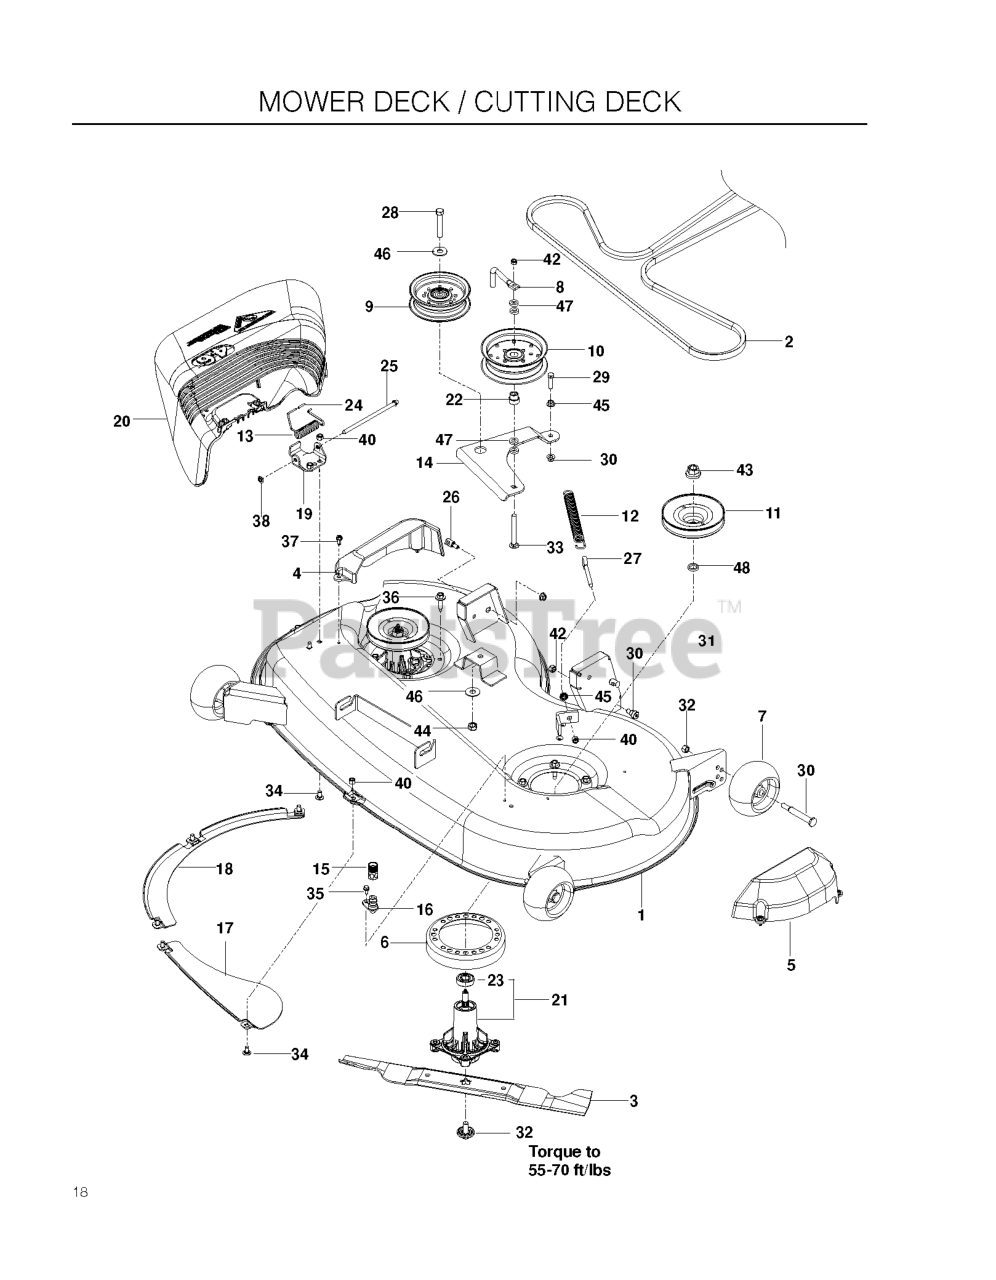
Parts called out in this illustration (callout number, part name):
1	DECK W/DECALS 46" ORANGE
3	BLADE.MOWER.46".HI.LIFT
4	COVER.MANDREL.RH.46"
5	COVER.MANDREL.LH.46"
6	STRIPPER-ROUND-UNIVERSAL
7	GAUGE WHEEL
8	BELT KEEPER 5"
9	PULLEY.IDLER.MWR.STATI.LH
10	PULLEY, IDLER
11	RP.PULLEY, DECK
12	SPRING, DECK BELT
13	TORSION SPRING
14	ARM, IDLER BLK
15	COUPLING.QUICK CONNECT
16	PORT.WASHOUT
17	BAFFLE CENTER FRONT
18	BAFFLE FRONT RH
19	BRKT.DEFLECTOR.38"2005+
20	SHIELD.DEFLECTOR.MOWER.46"BLAC
21	CUTTER HOUSING
22	IDLER BUSHING
23	REAR BRKT UTILITY BOX, PAINTED
24	CAP-SLEEVE
25	ROD, HINGE
26	STUD.FASTNER.W/ANTI-ROTATE
27	EYE BOLT 5/16 X 3.50
28	BOLT 7/16-14 X 2-1/2 GR 5 ZD
29	HCS 5/16C X 1 1/4
30	SHOULDER BOLT 1/2X2-5/8 ZD SPE
31	SB 3/8-16 X 3/8 SKT HD ZD
32	BOLT.WASHER.ASM.7/16-2
33	CARRIAGE BOLT 3/8-16 X
34	BOLT 5/16C X 3/4" CARRIAGE
35	SCREW #10 X 1/2 SELF TAPPING
36	WASHER HEAD SCREW
37	SCREW- 1/4-20 X 5/8
38	PUSH NUT
39	5/16-18 NYLOC FLANGE NUT
40	NUT 5/16 NYLOC
41	NUT 3/8-16 NYLOC
42	NUT HEX 3/8-16 NYLON, THIN
43	LOCKNUT - 9/16
44	7/16-14 HEX NUT W/NYL RING ZD
45	NUT 5/16C WHIZ
46	WASHER 7/16 FLAT ZD
47	WASHER 3/8 X 3/4 X .187 TK
48	WASHER-SPACER
